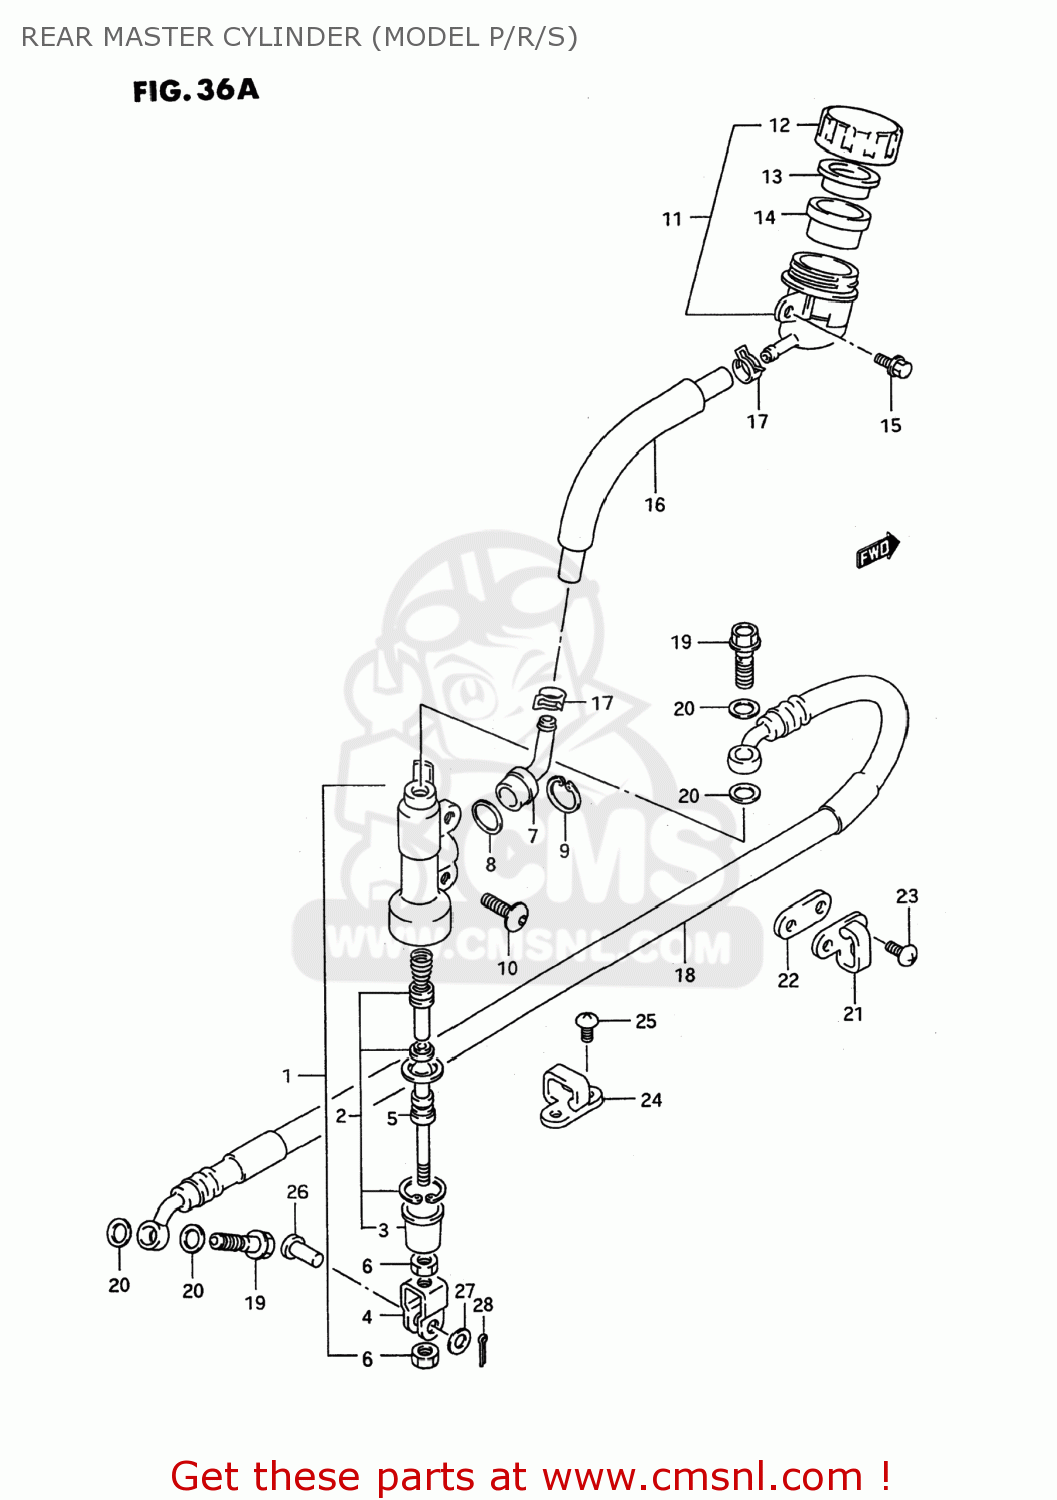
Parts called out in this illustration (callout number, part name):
1	CYLINDER ASSY,RR MASTER
2	PISTON/CUP SET
3	BOOT
4	YOKE
5	ROD,PUSH
6	NUT
7	CONNECTOR
8	O RING
9	CIRCLIP
10	SCREW(6X16)
11	TANK ASSY,RR BRAKE RESERVOIR
12	CAP
13	PLATE
14	DIAPHRAGM
15	BOLT
16	HOSE,TANK
17	CLAMP,RESERVOIR HOSE
18	HOSE,REAR BRAKE
19	BOLT UNION
20	WASHER(10X15X1.5)
21	GUIDE,RR BRAKE HOSE
22	SEAT,RR BRAKE HOSE GUIDE
23	SCREW
24	GUIDE,RR BRAKE HOSE
25	SCREW
26	PIN(8X20)
27	WASHER(8.5X13X1.6)
28	PIN
